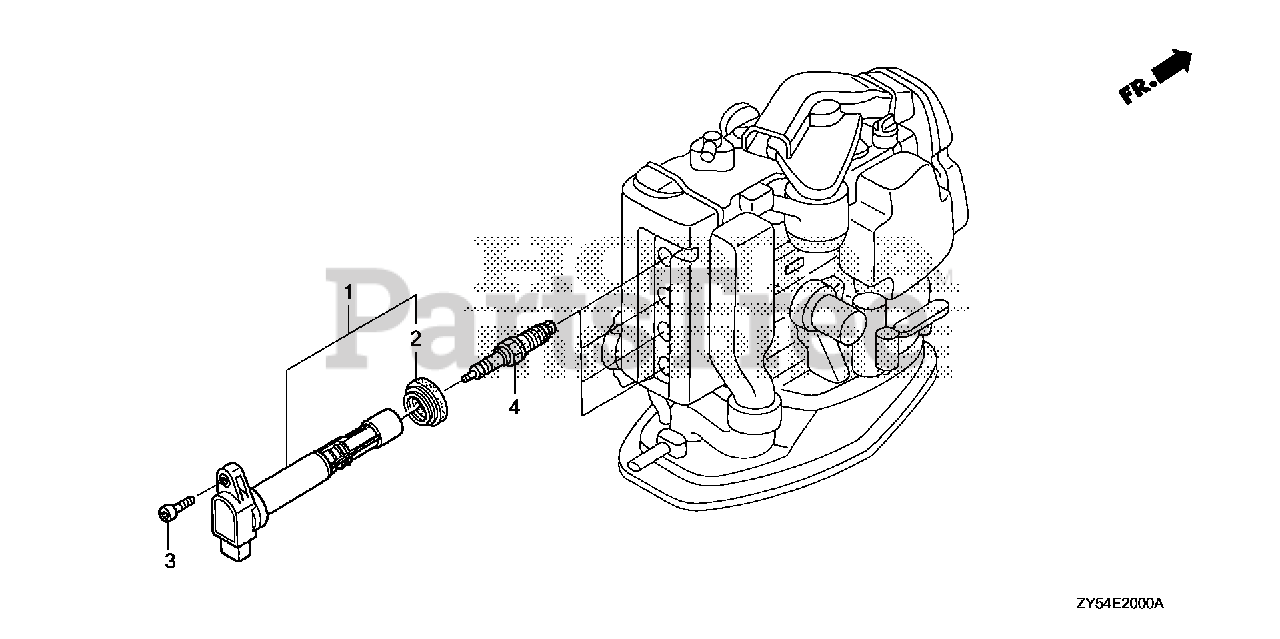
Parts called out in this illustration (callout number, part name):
1	COIL, PLUG HOLE
2	SEAL, PLUG HOLE
3	BOLT, SOCKET (6X25)
4	SPARK PLUG (SKJ20DR-M11) (DENSO)
4	SPARK PLUG (IZFR6K-11) (NGK)
4	SPARK PLUG (KJ20DR-M11) (DENSO)
4	SPARK PLUG (ZFR6K-11) (NGK)
